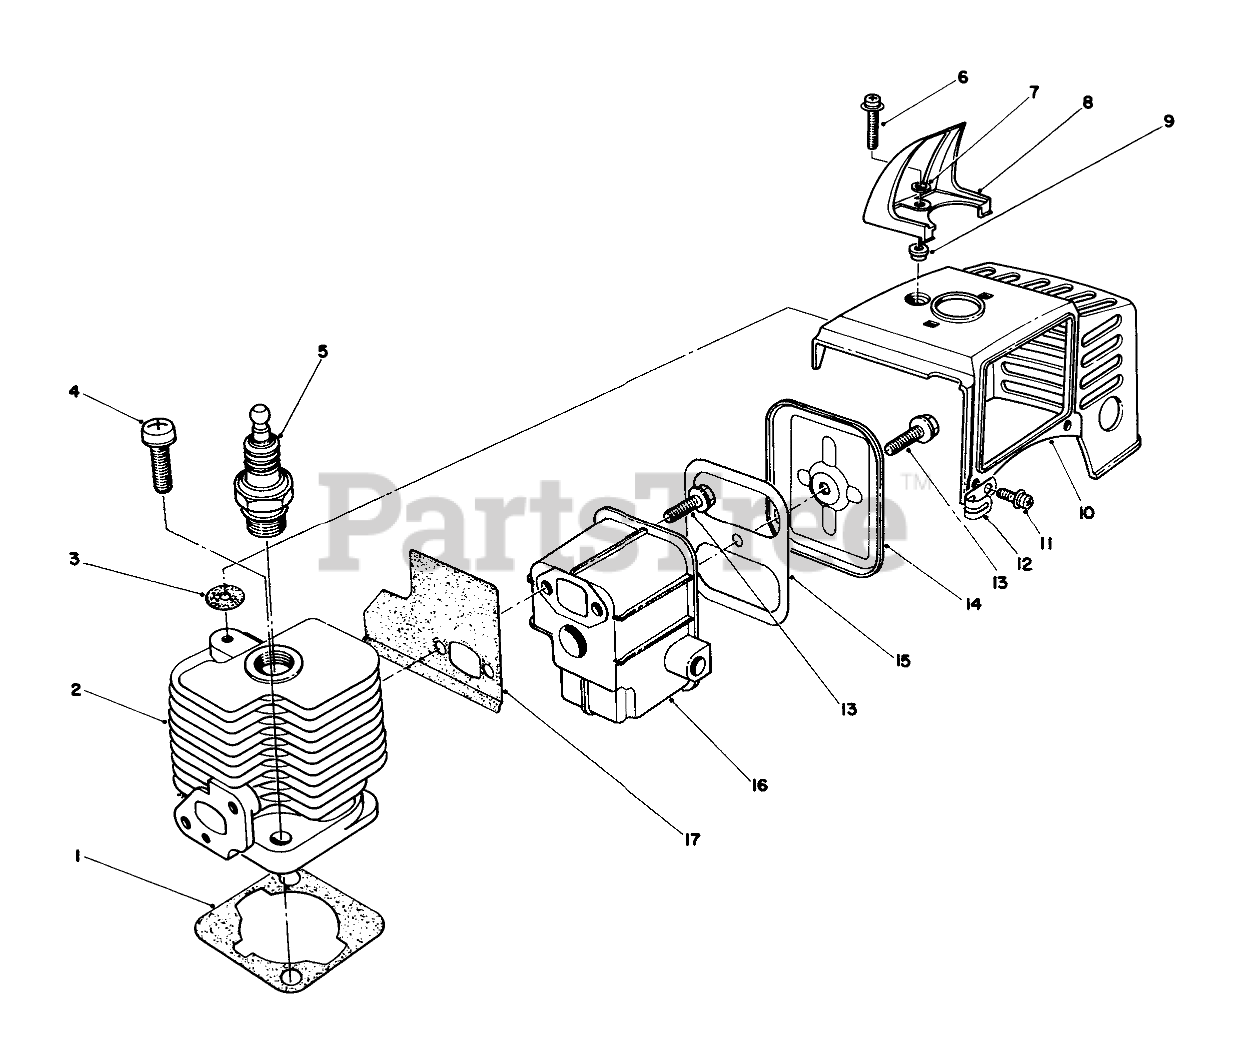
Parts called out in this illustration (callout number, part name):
1	CYL. GASKET
2	CYLINDER
3	GASKET
5	SPARK PLUG (NGK)
6	SCREW W/ WASHER
7	Washer
8	COVER
9	Bushing
10	TOP COVER
11	Screw
12	CLAMP
14	Lid-Muffler
15	MUFFLER GASKET
16	MUFFLER BODY
17	MUFFLER GASKET
